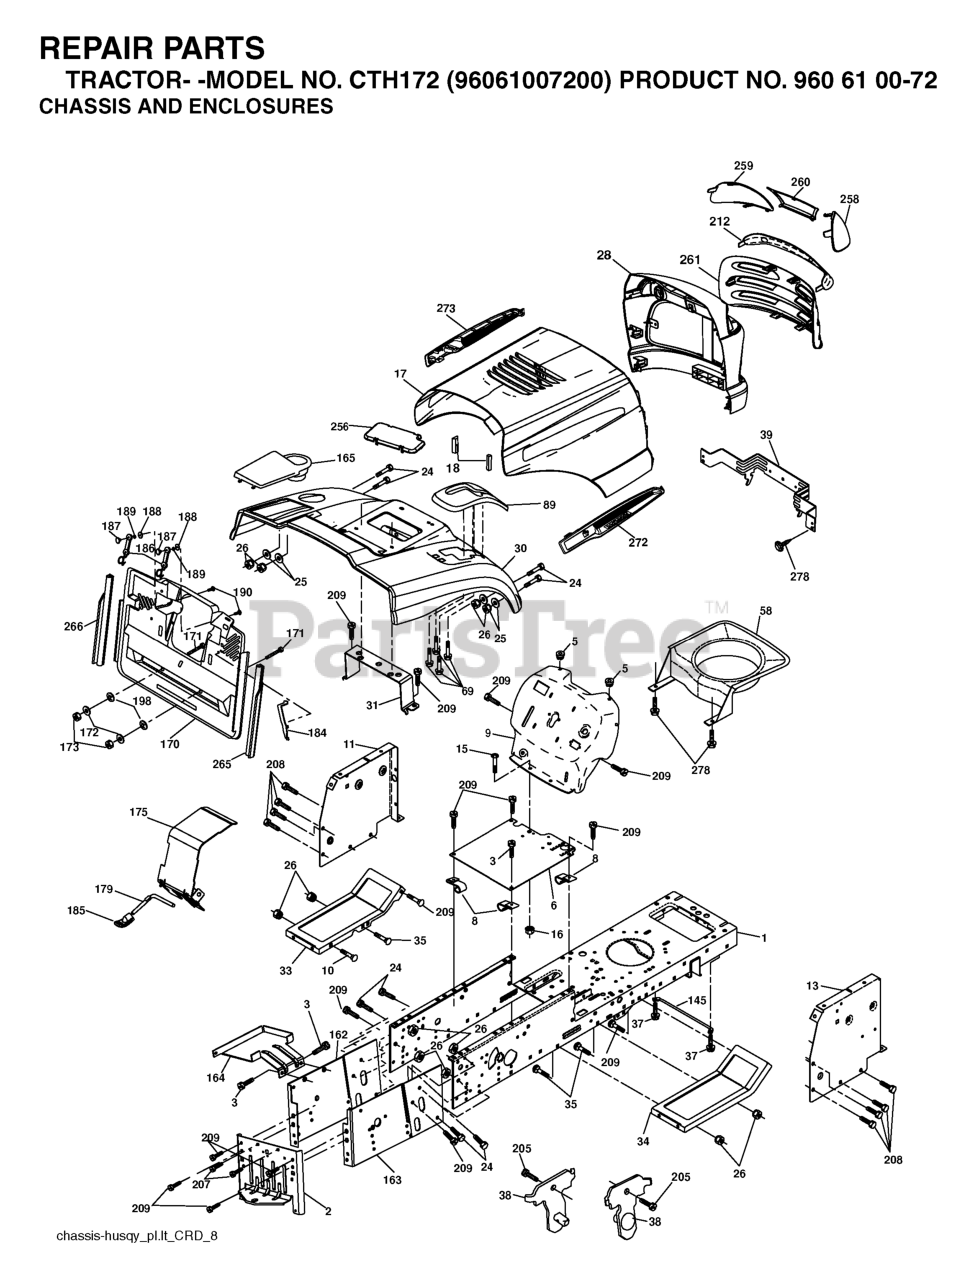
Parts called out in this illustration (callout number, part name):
2	DRAWBAR
3	SCREW 3/8-16X3/4
5	BUMPER.RUBBER.HOOD
6	PLATE
8	CLIP,INSULATOR
10	BOLT D
11	PANEL.DASH.LH.LTX
13	PANEL ASM, DASH RH
15	Screw, Machine, Truss Head 5/16-18 UNC x 3/4
16	NUT
17	VENT.HOOD.LASER.III
18	BUMPER.HOOD.LARGE.1.75"
25	WASHER
26	NUT
30	CONSOLE.CRD.AUTO.GRY
31	BRACKET SUPPORT FENDER
33	FOOTREST PNT LH
34	FOOTREST PNT RH
37	Screw 5/16-18 x 1/2 Hex, Self Tapping 5/16-18 x 1/2
38	BRACKET ASM PIVOT MOWER REAR
39	BRACKET PIVOT LASER
69	SCREW.HI-LO.CONSOLE
89	CONSOLE.CRD.AUTO.GREY.2005
145	ROD PIVOT CHASSIS/HOOD
162	BRACKET
163	BRACKET EXTEN CHASSIS RH CRD
165	RP.COVER.BATTERY.CRD.GREY
172	WASHER
175	DOOR TRAP
179	ROD PIVOT FBI
184	BRACKET.ACTUATOR.BAGGER.SRD
186	LATCH ASSY
187	WELDNUT
189	LOCKWASHER #10
190	SCREW
207	SCREW, 5/16-18 X 1/2
208	SCREW 3/8-16X1/2
209	SCREW, 3/8-16X3/4
212	INSERT.LENS.REFLECTIVE
256	COVER FENDER CRD
258	LENS LH
259	LENS LH
260	COVER.LENS.HUSQ.LASER
265	SEALING
266	SEALING
272	VENT.HOOD.LASER.
273	VENT.HOOD.LASER.
278	SCREW
